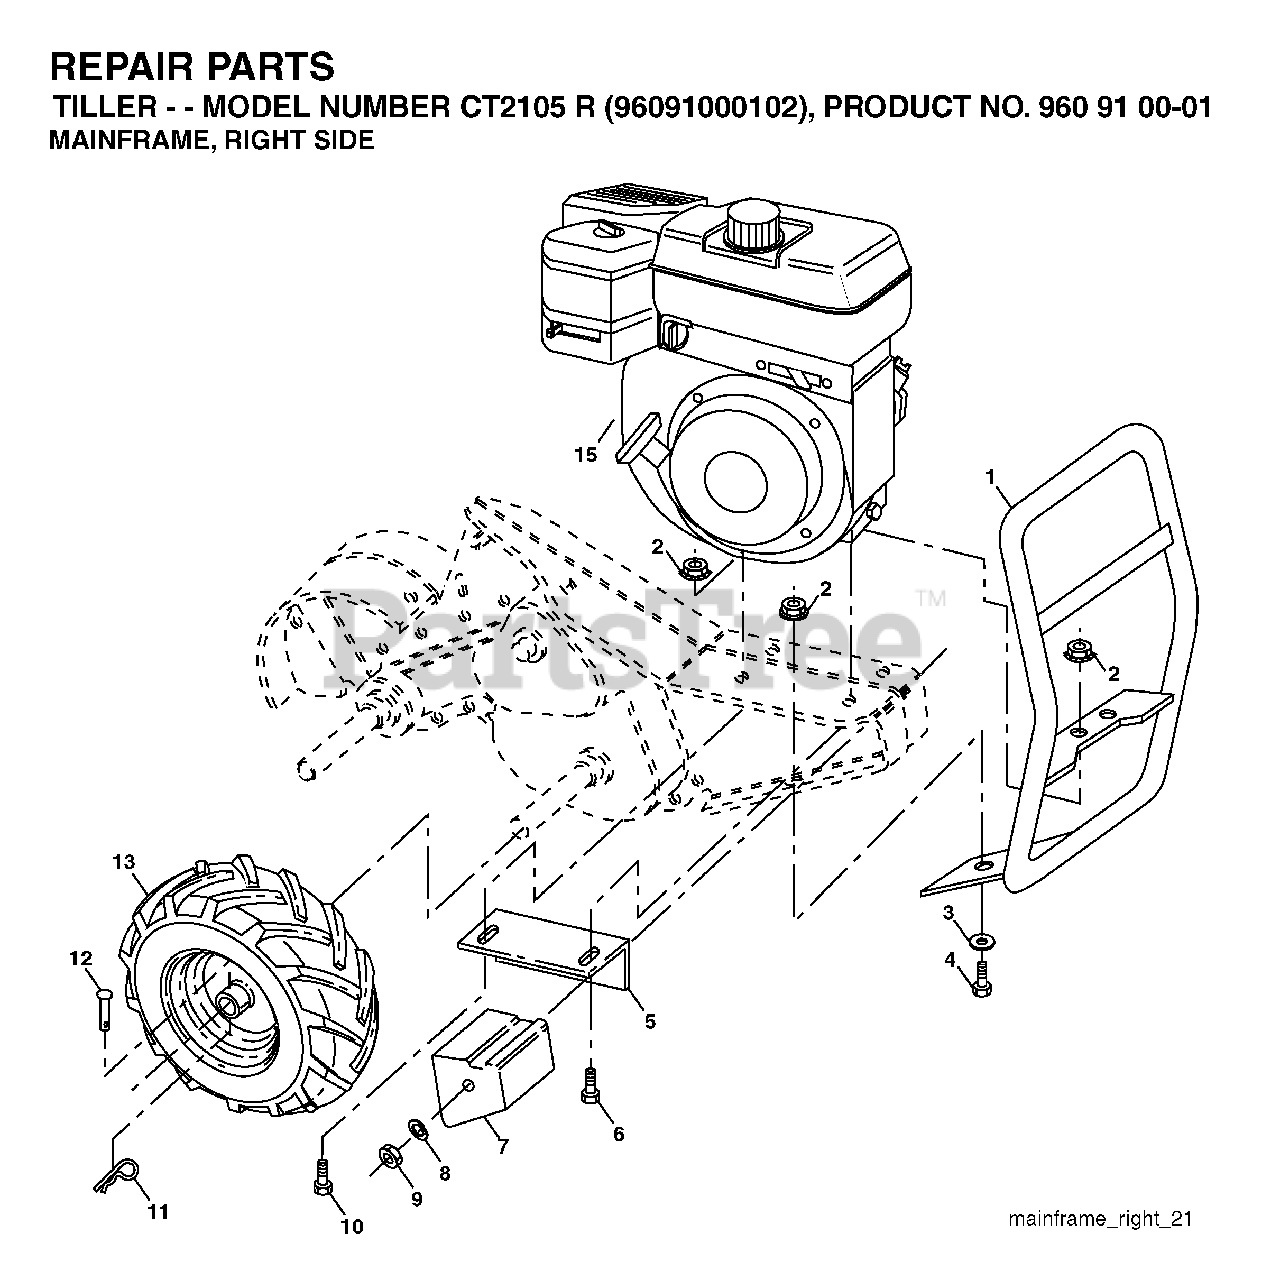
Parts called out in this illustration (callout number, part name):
1	BUMPER.ASM.TILLER.
2	LOCKNUT-FLANGE 5/16-18
3	WASHER
4	BOLT
5	BRACKET RH CRT
6	BOLT, HEX 5/16-18X1-3/4
7	COUNTERWEIGHT, RH
8	WASHER, LOCK 3/8
9	NUT.HEX.3/8-16UNC
10	BOLT
11	RETAINER M
12	RIVET,DRILLED
5321243-66	RIM
5321247-18	VALVE STEM LT
